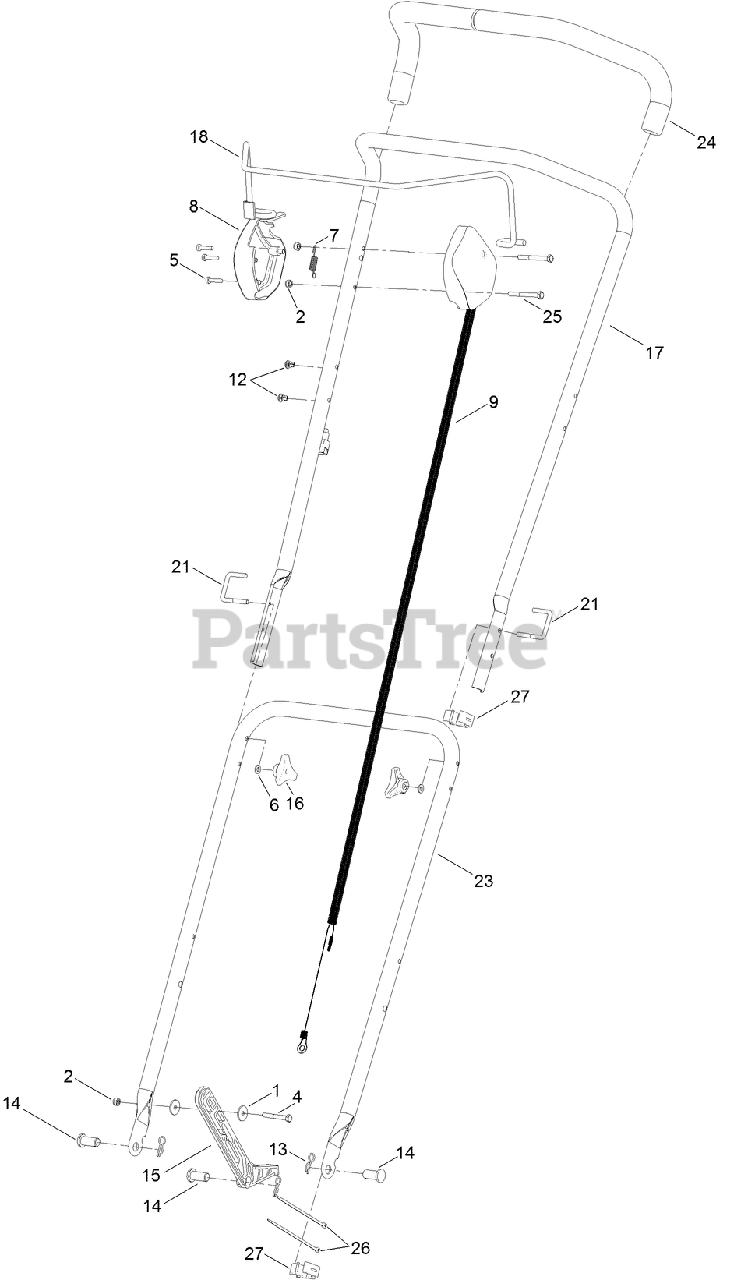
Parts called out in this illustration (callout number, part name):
1	WASHER
2	NUT-NYLOC
4	BOLT-HH
5	SCREW-PLASTITE
7	SPRING-RETURN
8	BOX-SWITCH, LH
9	OPC WIRE LOOM ASM
12	FASTENER-DRIVE
13	CLIP-R
14	PIN-RETAINING
15	FOOTSTOP
16	HANDWHEEL
17	HANDLE-UPPER
18	ARM-BAIL
21	BOLT-U
23	HANDLE-LOWER
24	GRIP-HANDLE
25	BOLT-HEX
26	TIE-CABLE
27	GUIDE-CABLE
